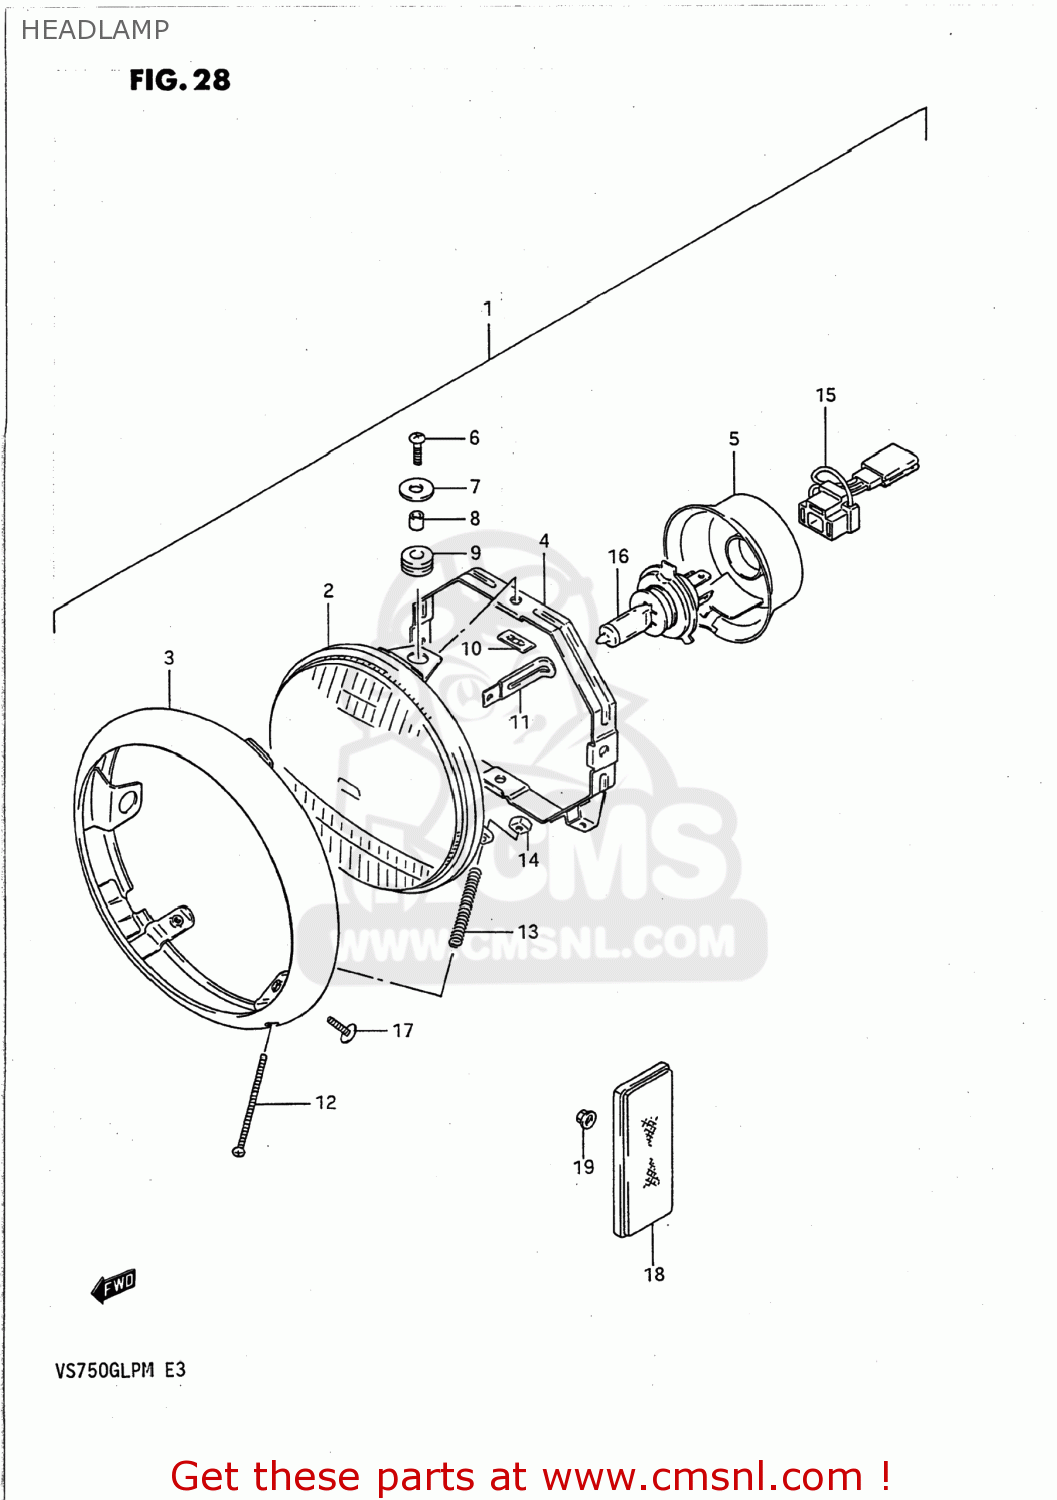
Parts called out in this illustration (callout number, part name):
1	HEADLAMP ASSY
2	UNIT,LAMP
3	RIM
4	RING,MOUNTING
5	COVER,SOCKET
6	SCREW(5X14)
7	WASHER
8	SPACER
9	CUSHION
10	NUT
11	CLAMP
12	SCREW,HEADLAMP ADJUST
13	SPRING,HEADLAMP ADJUST
14	NUT
15	SOCKET
16	BULB(12V60/55W,H4)
17	SCREW(5X12)
18	REFLEX REFLECTOR,FR SIDE
19	NUT
